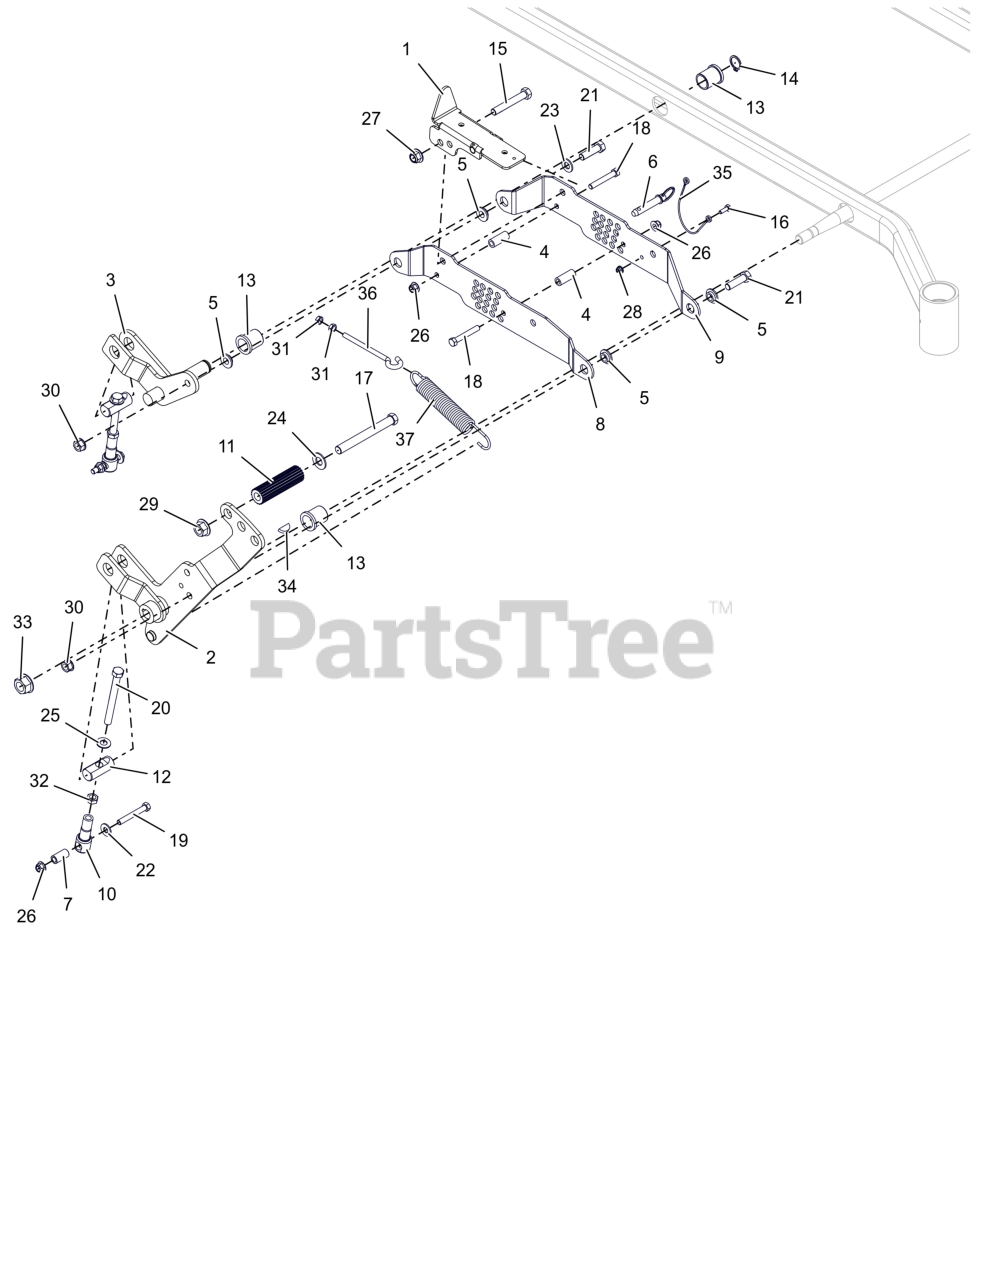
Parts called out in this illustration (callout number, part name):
1	MECHANICAL LOCK-UP WMT - BLACK
2	FRT RH DECK LIFT ARM WMT- LF
3	WLDMT, REAR RH DECK LIFT ARM
4	SPACER, .375 X .625 X 1.54
5	BSHG-FLG .515X.750X.310X1.120
6	PIN, .50 X 2.00 USABLE LG BALL
7	SPACER, DECK LEVELING
8	RH OTBRRD LIFT/CUT HT BRKT-BLK
9	RH INBRD LIFT/CUT HT BRKT-BLK
10	LINK, DECK LIFT FORMED
11	ROD, FOOT PEDAL (BLACK)
12	PIN, DECK LIFT
13	BSHG-FLG 1.00X1.25X1.50X1.50
14	RG-RTNG-EXT 1.00X.078
15	BLT,HEX .50-13X3.25 G5 ZCC
16	BLT, HEX .25-20X.75 G5 ZCC
17	BLT, HEX .62-11X5.50 G5 FBP
18	BLT, HEX .38-16X2.50 G5 ZCC
19	BLT, HEX .38-16X2.75 G8 ZCC
20	BLT, HEX 0.5-13X5S GR5 ZCC
21	BLT, HEX .50-13X1.75 G5 ZCC
22	WSHR,FLT .438X1.00X.083 ZCC
23	WSHR,FLT .531X1.062X.095 ZCC
24	WSHRFLT 5/8SAE CARBHARD FBP
25	WSHR, FLT .557X1.040X.102 ZCC
26	NUT,NYL-FLG .38-16 GF ZCC
27	NUT,NYL-FLG .50-13 GF ZCC
28	NUT,NYL-FLG .25-20 GF ZCC
29	NUT,FLG-TOP LK .625-11 FBP
30	NUT-LK-CTR-FLG .500-13 GG ZCC
31	NUT-JAM .375-16 G2 ZCC
32	NUT-JAM .500-13 G2 ZCC
33	NUT,FLG-TOP LK .625-11 FBP
34	KEY-WDRF .25X1.00 HRD #15
35	CABLE, 12.0 LANYARD, NYLON
36	BOLT,.38-16 X 4.25-.62 DIA EYE
37	SG-TENS .162X1.25X8.25 WLD 25
